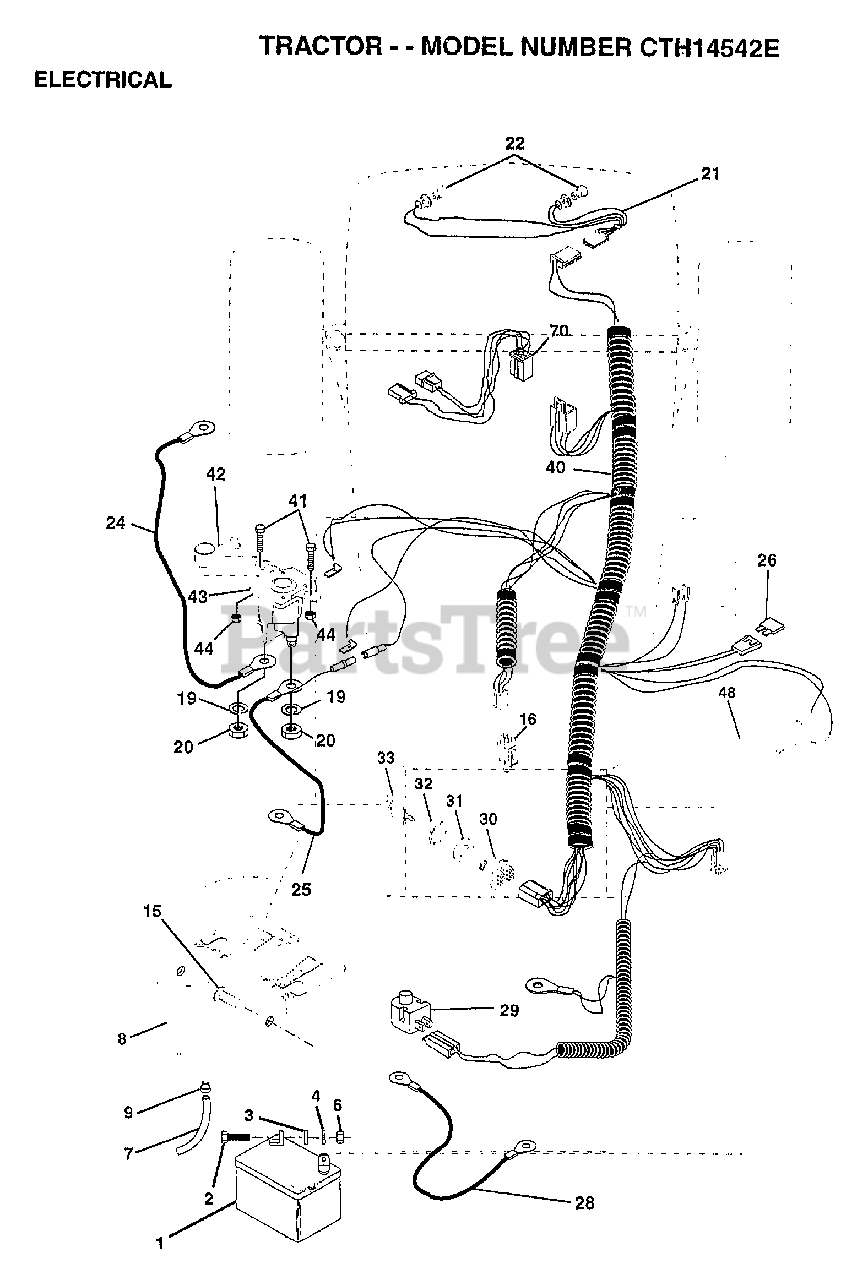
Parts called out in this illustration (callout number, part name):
2	BOLT LT
3	WASHER
4	LOCKWASHER
7	TUBE T
8	"CASE,BATTERY.MECH"
9	HOSE CLAMP T
15	FASTNER.SNAP-IN
16	SWITCH INTERLOCK
20	NUT
21	"HARNESS,LIGHT SOC"
22	HEADLAMP BULB
24	CABLE.BTRY.6GA.38
25	CABLE.BTRY.6GA.RD
26	FUSE HYT
28	CABLE T
29	SWITCH SEAT
30	SWITCH IGN 4POS
31	NUT IGNITION
32	COVER KEY SWITCH
33	KEY
40	HARNESS IGNITION
41	BOLT HXHD FIN
44	NUT HXKEP 1/4X20
48	ADAPTER AMMETER
70	HARNESS.ENG.DUAL
